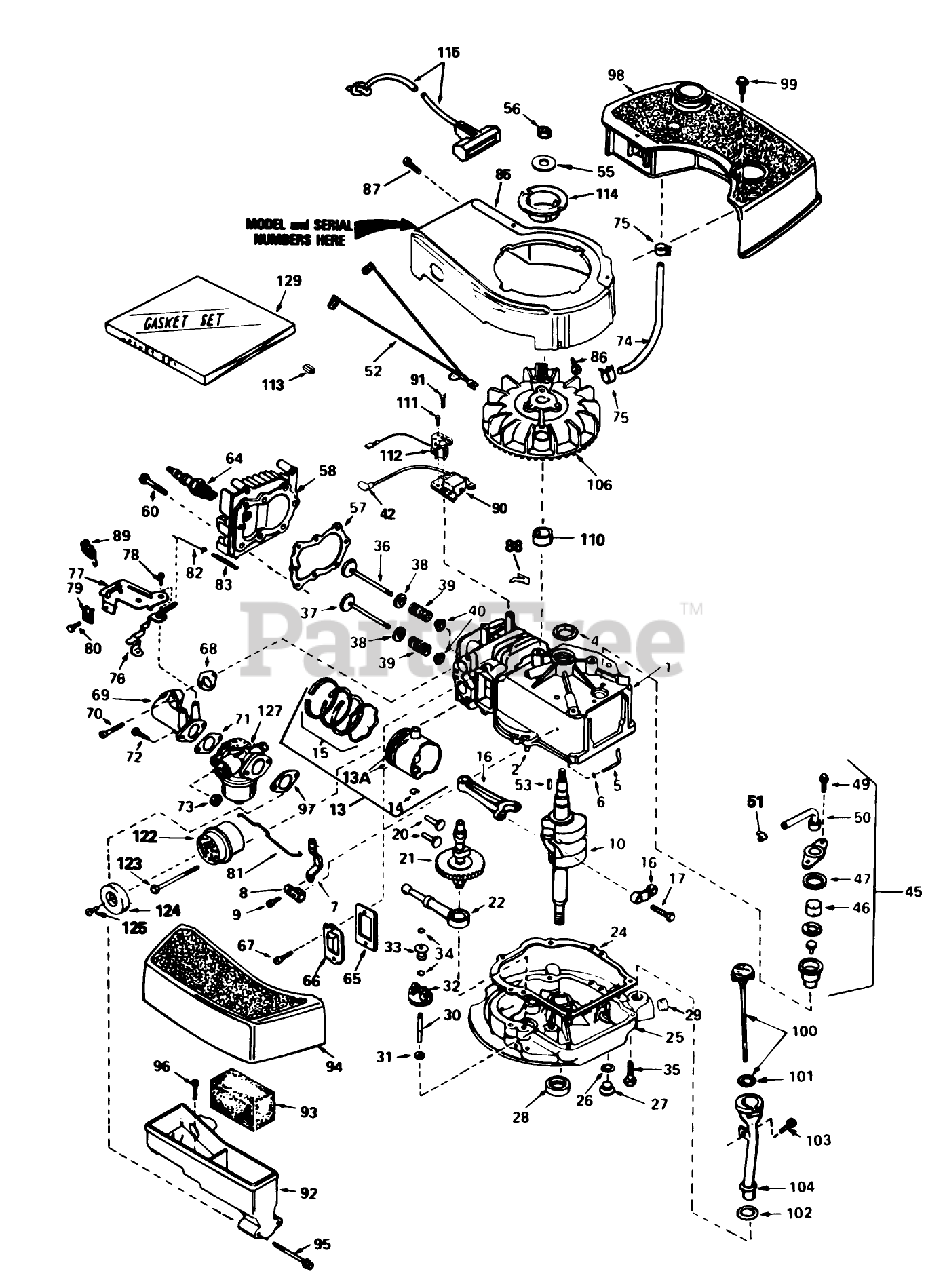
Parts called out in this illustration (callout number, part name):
1	Cylinder Assy. (Incl. #24)
2	Pin-Dowel
4	Seal-Oil
5	Rod, Governor (Incl. No. 36)
6	Washer-Flat
7	Governor Lever
8	Clamp-Lever, Governor
9	Screw
10	Crankshaft
13	Piston, Pin Ring Assy. (Std.) (Incl. Ref. #13A, 14 15)
13	Piston, Pin Ring Assy. (.010 oversize) (Incl. Ref. #13A, 14 15)
13	Piston, Pin Ring Assy. (.020 oversize) (Incl. Ref. #13A, 14 15)
13A	Piston Pin Assy. (Incl . Ref. . #14) (Std.)
13A	Piston Pin Assy. (Incl. Ref. #14) (.010 Oversize)
13A	Piston Pin Assy. (.020 oversize) (Incl. Ref. #14)
14	Ring-Retaining, Piston Pin
15	Ring Set (Std.)
15	Ring Set (.020" OS)
15	Ring Set (.010" OS)
16	Rod Assy., Connecting (Incl. Ref. #17)
17	Bolt-Rod, Connecting
20	Lifter-Valve
21	Camshaft(Mech.Comp. Release)
22	Oil Pump ASM
24	Gasket, Mounting
25	Flange Assy.-Mounting (Incl. Ref. #26, 27, 28 31)
26	Gasket-Oil Drain
27	Plug Oil Drain
28	Seal Oil
29	Plug-Pipe
30	Shaft-Governor
31	Washer-Flat
32	Governor Gear ASM
33	Spool-Governor
34	Ring-Retaining
35	Screw (1/4-20 x 1-1/4)
36	Valve, Intake (Std.) (Incl. Ref. #40)
36	Valve, Intake (1/32" oversize)(Incl. No. 40)
37	Valve, Exhaust (Std.)(Incl. No. 40)
37	Valve, Intake (1/32" oversize)(Incl. No. 40)
38	Cap-Upper Valve Spring
39	Spring-Valve
40	Cap-Valve, Spring
42	Cover-Spark Plug
45	Breather Assy. (Incl. Ref. #46 thru 51)
46	Element-Breather
47	Gasket-Breather
49	Screw (10-24 x 9/16)
50	Tube, Breaker
51	Clip, Breather
52	Wire-Ground
53	Key-Flywheel
55	Washer-Belleville
56	Nut-Flywheel
57	63573 GIL 42 SNWTHW
58	Head-Cylinder
60	Screw (5/16-18x1-1/2)
64	Plug, Spark (Autolite 458, Champion J-19LM or equiv.)
65	Gasket-Breather
66	Cover-Valve
67	Screw
68	Gasket-Intake
69	Pipe, Intake (Incl. No. 68)
70	Screw (1/4-20 x 1)
71	Gasket-Carburetor
73	Nut and Lock Washer (1/4-28)
74	Line-Fuel
75	Clamp-Line, Fuel
76	Lever Control
77	Control Assy., Speed (Incl. Nos, 76, 78 89)
78	Screw, Hex Washer Hd Shoulder Self-Tap
79	Conduit
80	Screw (10-32 x 3/8)
81	Link-Throttle
82	Link Governor Spring
83	Spring Governor
85	Housing, Blower
86	Screw (1/4-20x19/32)
87	Screw (10-24 x 9/16)
88	Clip-Wire
89	Terminal
90	Solid State
91	Screw
92	Body Air Cleaner
93	Filer, Air
94	Cove, Air Cleaner
95	Screw Fil Hd.
96	Screw, Hex Washer Hd Shoulder Self-Tap
97	Gasket-Air Cleaner
98	Tank-Fuel
99	Screw (10-32 x 35/64)
100	Dipstick, Oil (Incl. Ref. #101)(Twist Lock)
101	O-Ring
102	Gasket
103	Screw (10-32 x 1/2)
104	Tube-Oil Fill
106	Flywheel
110	Spacer
111	Screw (8-32x27/64)
112	Coil, Alternator
113	Terminal
114	Hub-Starter
115	Rope Assy., Starter
122	Muffler (Incl. Ref. #122)
123	Screw
124	Cover-Muffler
125	Screw
127	Carburetor (Incl. Ref. #71)
129	Gasket Set
